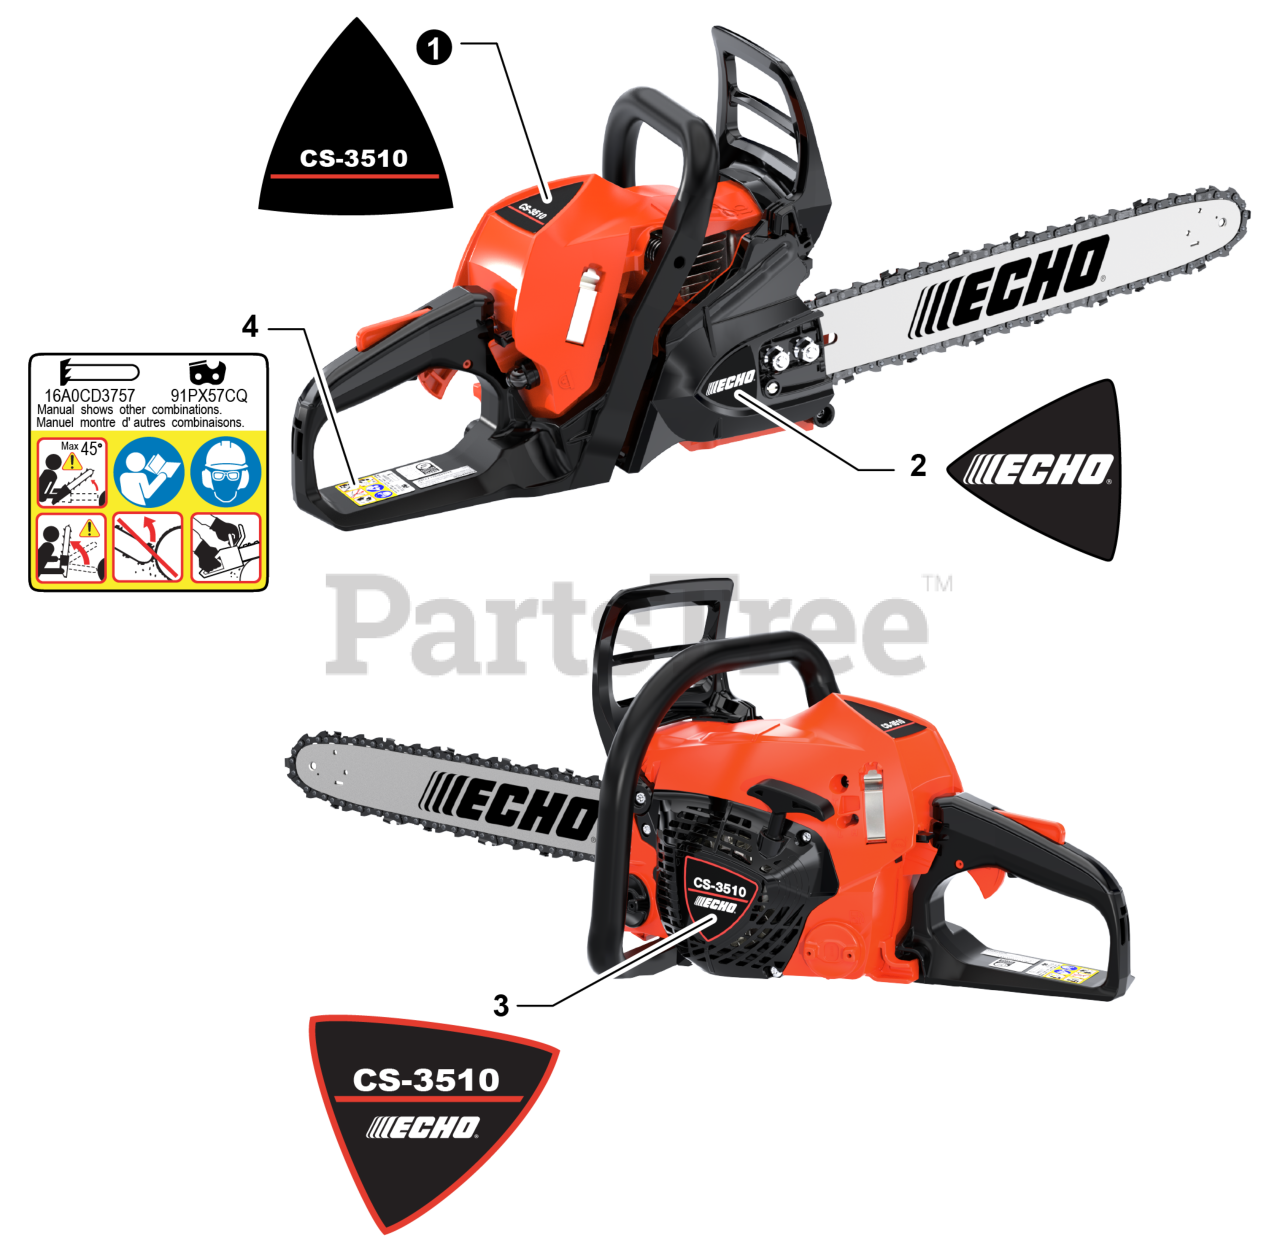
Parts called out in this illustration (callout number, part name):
1	LABEL - MODEL CS- 3510
2	LABEL - ECHO
3	LABEL - RECOIL STARTER
4	LABEL - CAUTION
